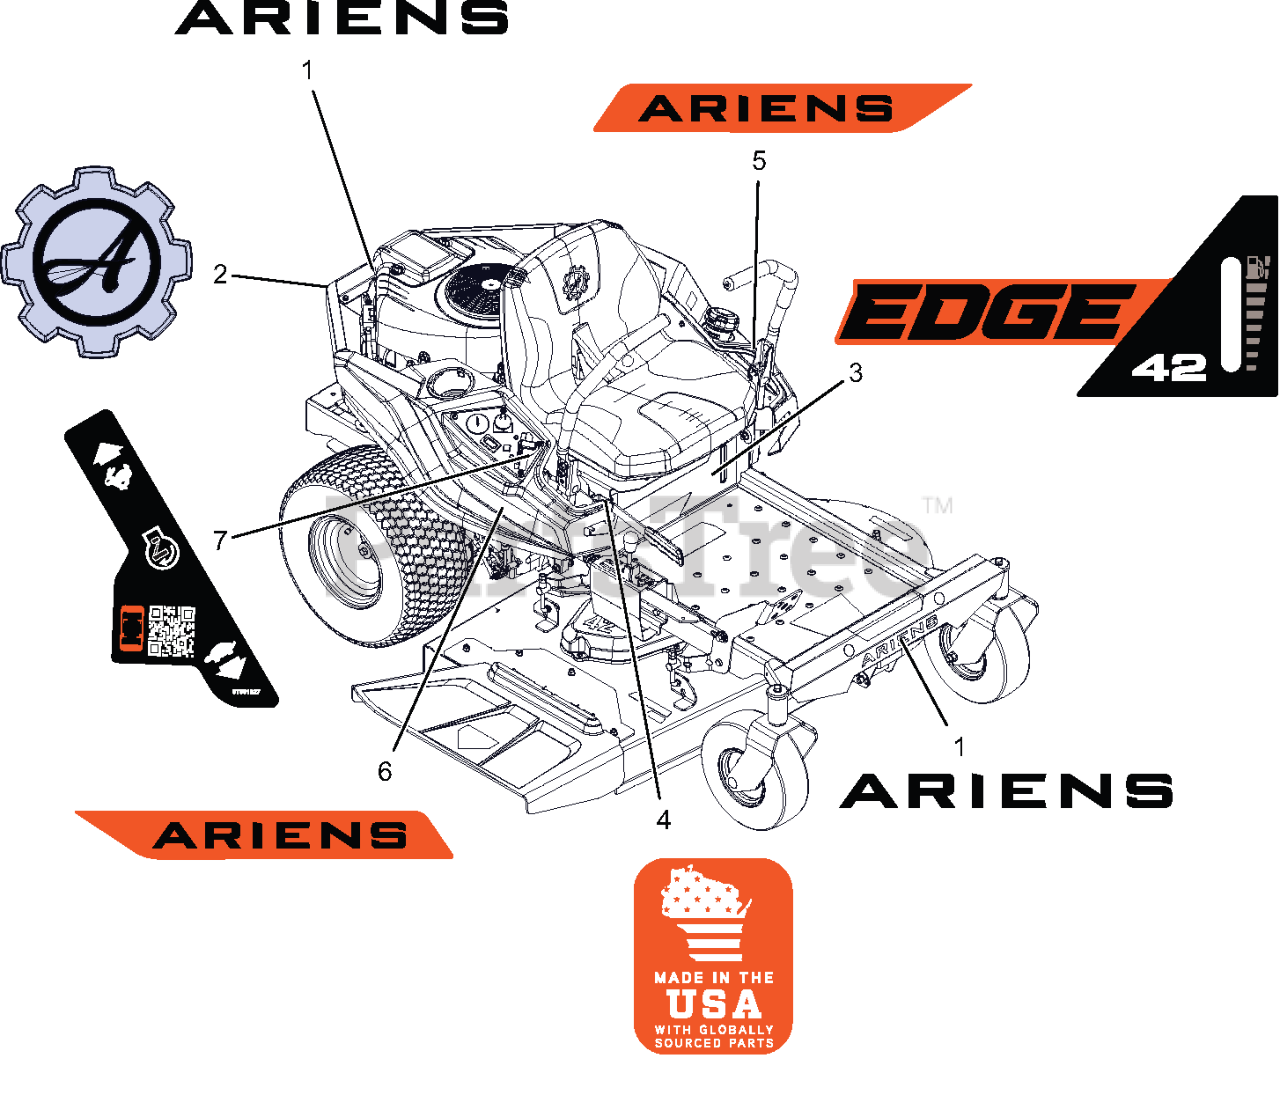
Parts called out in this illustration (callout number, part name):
1	DECAL- ARIENS 9.625" BLACK
2	DECAL- ARIENS GEAR BADGE
3	DECAL- EDGE 42 KICKPLATE
4	DECAL- MADE IN USA
5	DECAL- ARIENS (FENDER LH)
6	DECAL- ARIENS (FENDER RH)
7	DECAL- THROTTLE CONTROL EDGE
